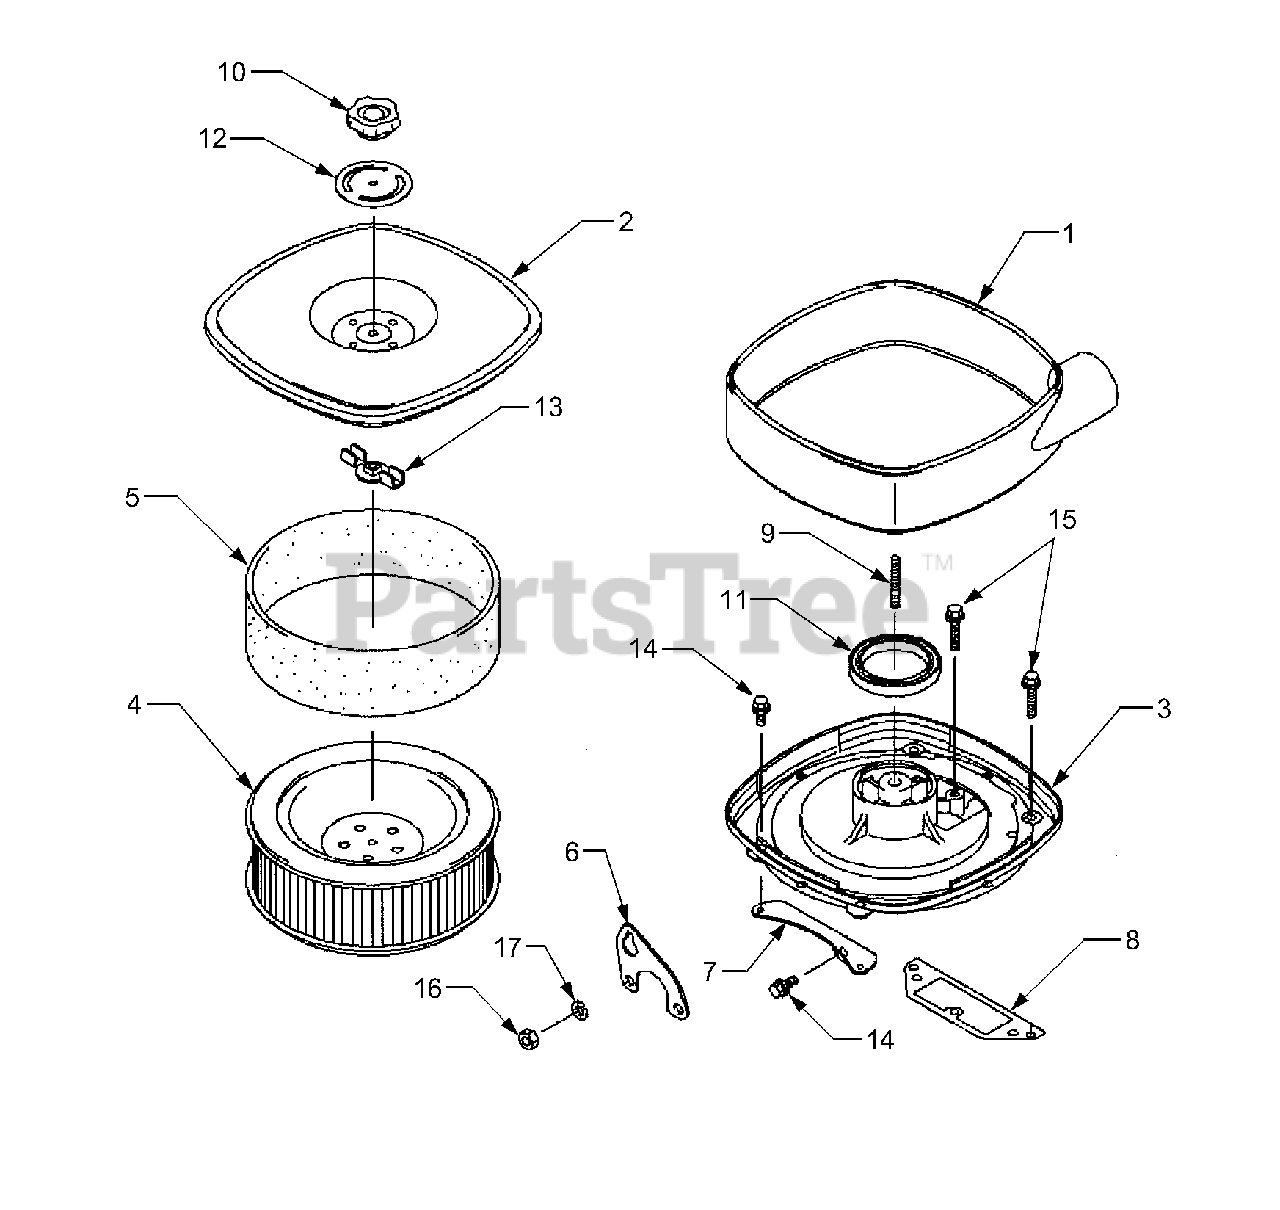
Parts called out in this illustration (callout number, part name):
1	Case, Air Filter Body
2	Case, Air Filter Upper
3	Case, Air Filter Lower
4	Element, Air Filter
5	Precleaner, Foam
7	Bracket, Air Filter
8	Gasket, Air Filter
11	Seal
14	Bolt, Flanged
15	Bolt, Flanged
17	Washer, Spring
